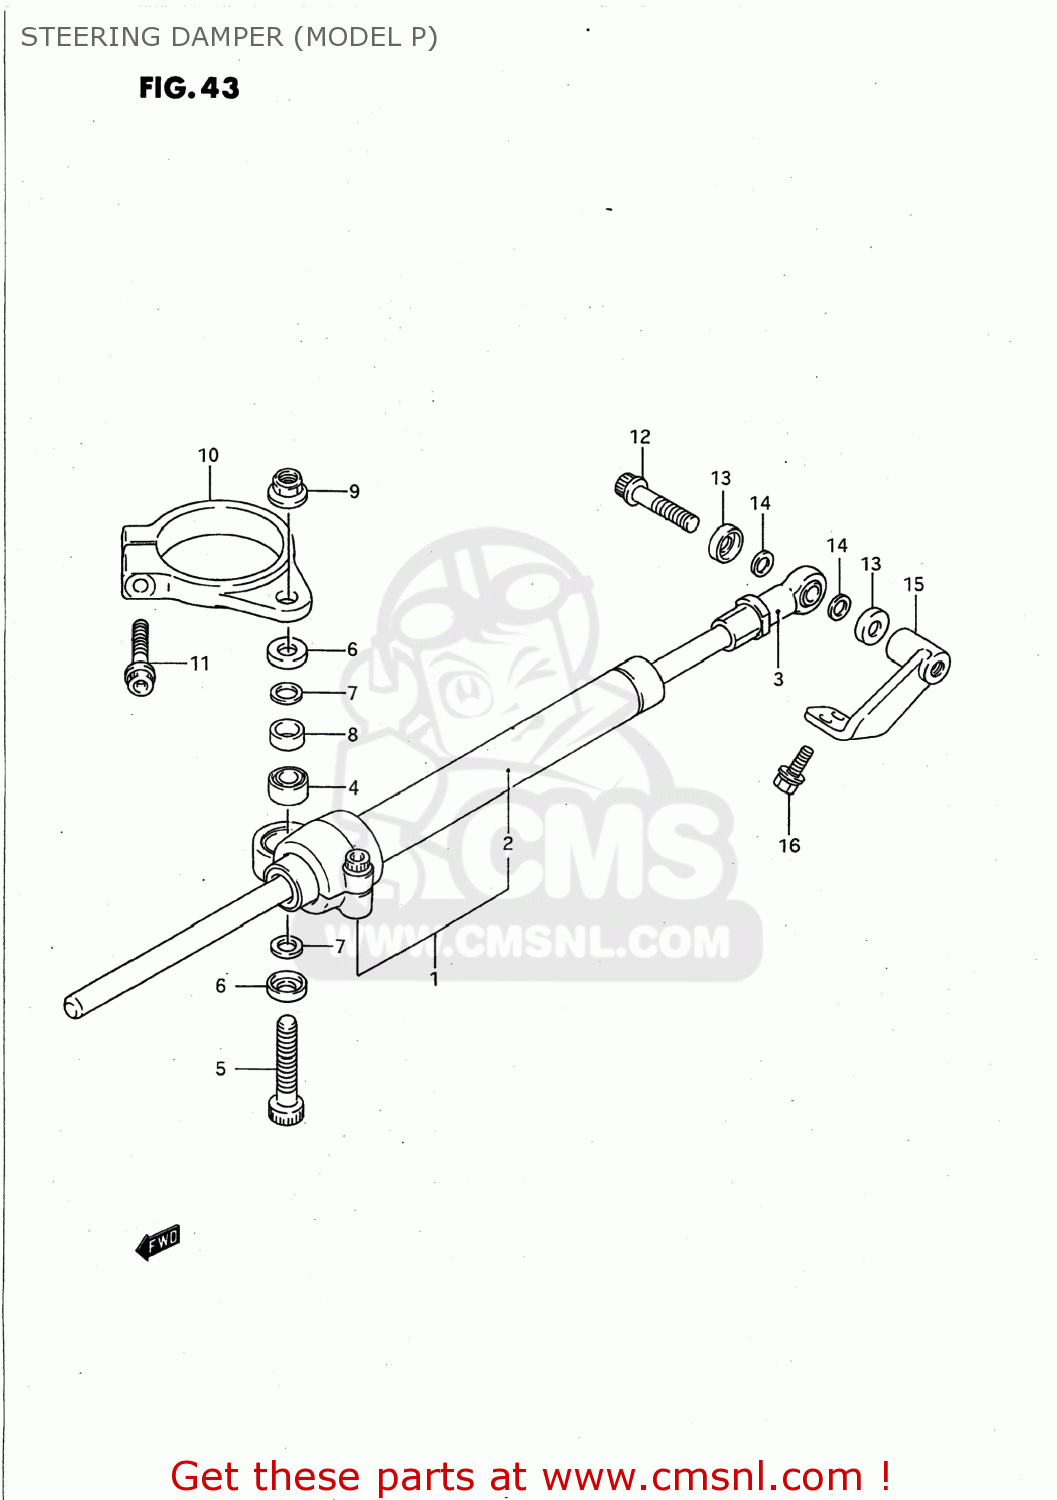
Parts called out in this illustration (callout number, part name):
1	DAMPER ASSEMBLY,STEERING
2	DAMPER,STEERING
3	PILLOW BALL,ROD END
4	BEARING(8X17.5X11)
5	BOLT
6	7
7	SHIM
8	SPACER (8.4X14X6)
9	NUT
10	BRACKET,STEERING DAMPER
11	BOLT
12	BOLT
13	14
14	SHIM
15	BOSS,STEERING DAMPER
16	BOLT
